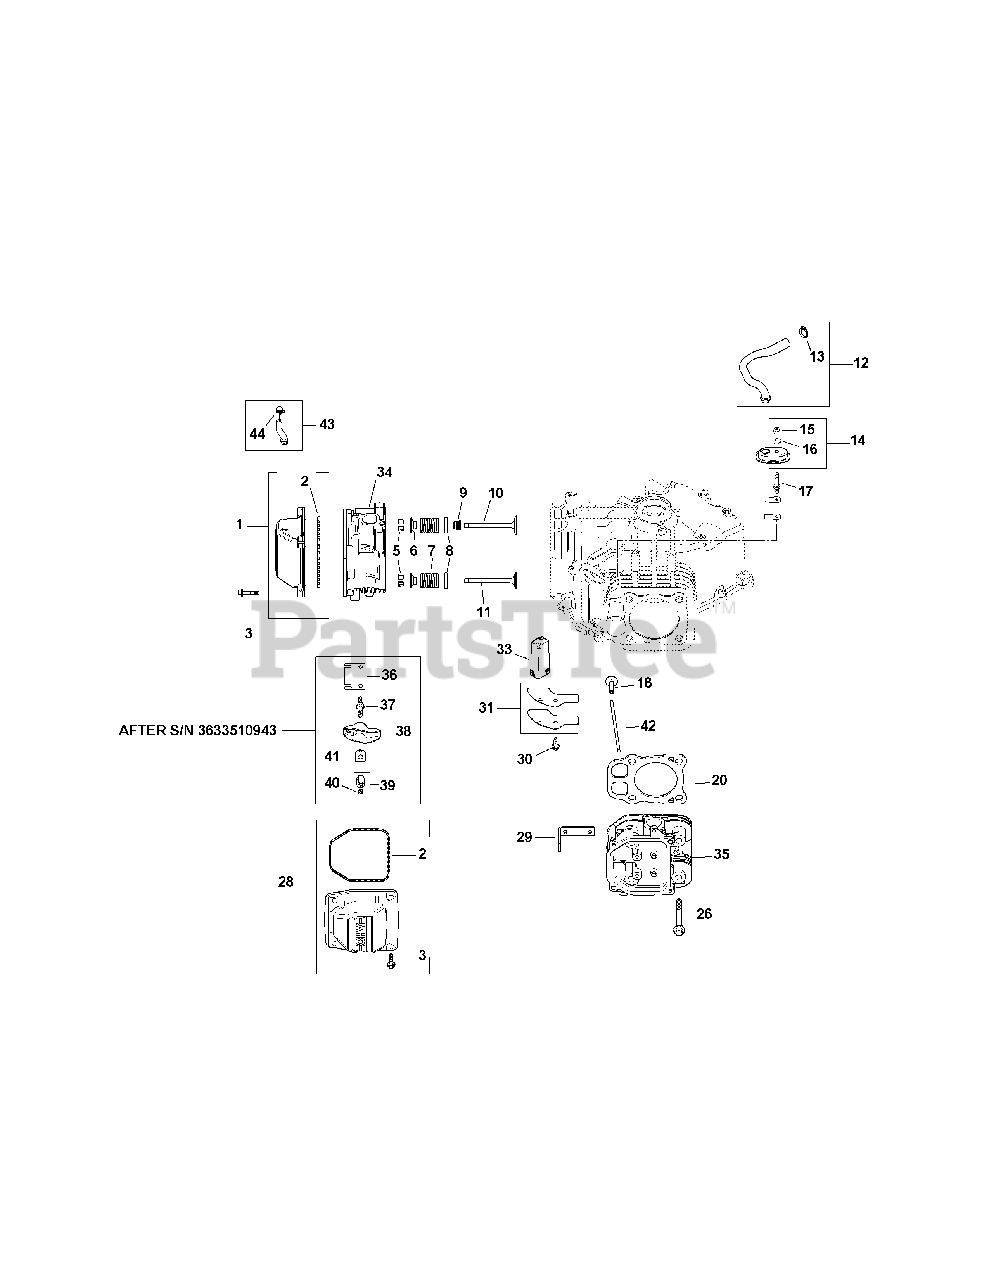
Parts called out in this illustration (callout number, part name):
1	Breather Valve Cover Kit (Inc. 2)
2	Valve Cover O-Ring
3	Flg. Screw, M6 x 1.0 x 30
5	Retainer Kit
6	Valve Spring Cap
7	Valve Spring
8	Spring Retainer
9	Valve Stem Seal
10	Intake Valve
11	Exhaust Valve
12	Breather Hose Kit (Inc. 13)
13	Hose Clamp, 1/2
14	Breather Housing Kit (Inc. 15 & 16)
15	Lock Nut, M5 x .8
16	Sealing Washer
17	Breather Cover Stud
20	Cylinder Head Gasket Kit
26	Flg. Screw, M10 x 1.5 x 90
28	Breather Valve Cover Kit (Inc. 2 & 3)
29	Lifting Strap
30	Flg. Thd. Frm. Screw, M6 x 1.0 x 16
31	Breather Cover Kit (Inc. 32)
33	Breather Filter
34	#1 Cylinder Head Assembly Kit
35	#2 Cylinder Head Assembly Kit
39	Hex Nut Assembly (Incl. 39)
41	Rocker Arm Pivot
43	Fuel Pump Hose Kit w/Clamp (Inc.44)
